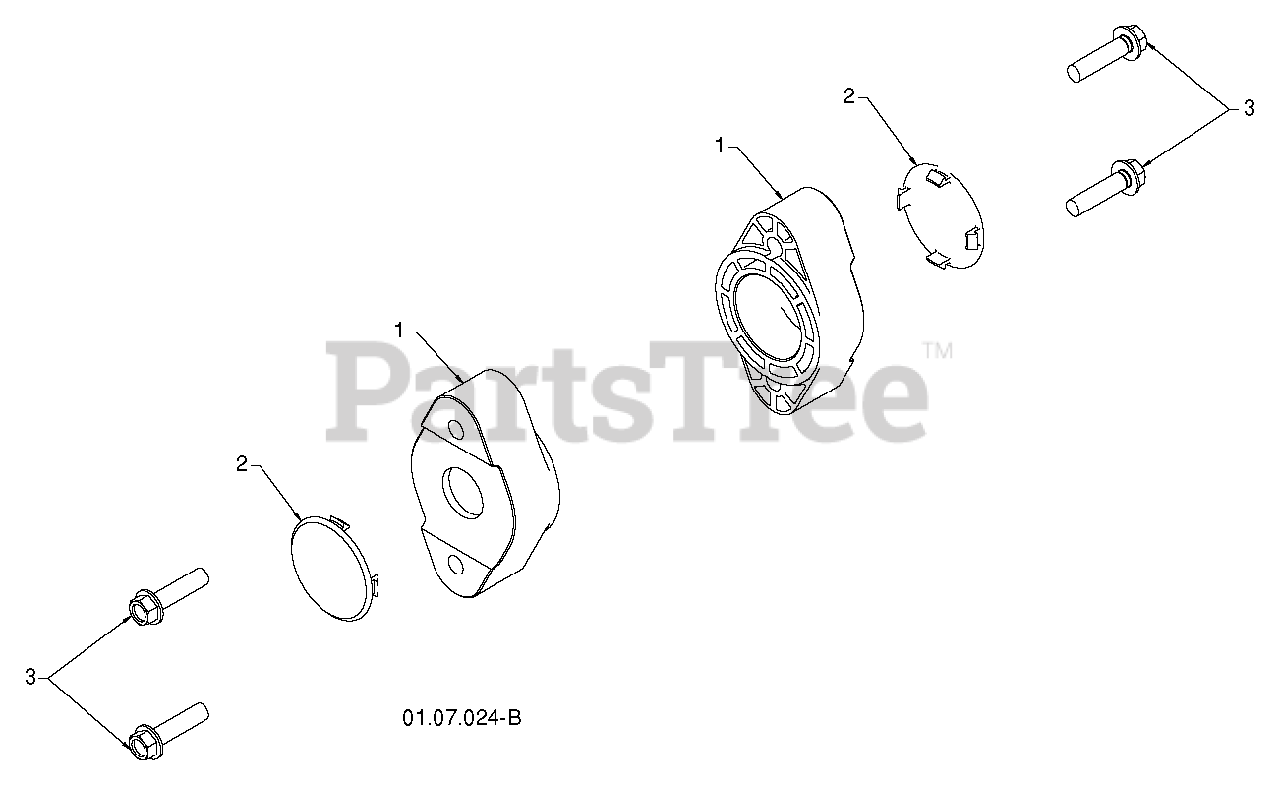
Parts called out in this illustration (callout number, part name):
1	BEARING.AUGER.SHAFT
2	PLUG.BEARING.HOLE.HSG
3	SCREW, HEX HD 5/16X1
